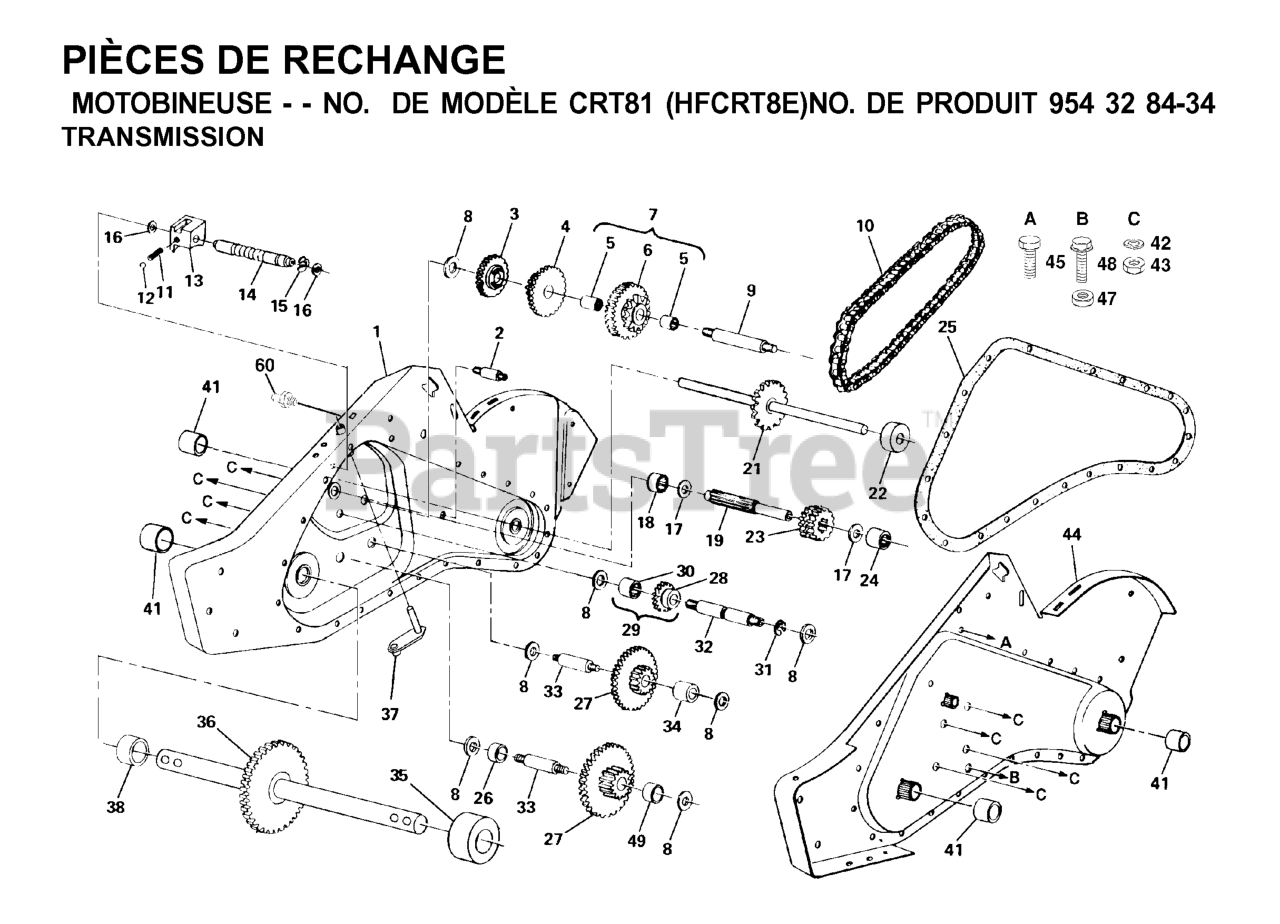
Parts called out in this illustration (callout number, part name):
1	GAERCASE.ASM.RH.W/BEARING
3	GEAR.REVERSE.8HP
5	BEARING.NEEDLE.CRT
6	SPROCKET ASMBLY, TINE
7	SPROCKET ASMBLY W/BEARINGS
9	SHAFT.REDUCTION.TILLER
10	CHAIN.ROLLER.TILLER
11	SPRING-SHIFT CRT
12	STEEL BALL KIT
13	SHIFT FORK TI
14	SHAFT.SHIFT.1.00 PINION
16	WASHER, SEAL (2 2)
17	THRUST WASHER
18	BEARING TI
19	SHAFT INPUT
21	SHAFT TINE CRT
22	SPACER 1.008X1-3/4X.645
23	GEAR.PINION
24	NEEDLE BRNG LT
25	RP GASKET, GEARCASE
27	GEAR, CLUSTER CRT
28	REVERSE GEAR
29	GEAR ASMBLY, REVERSE IDLER
30	NEEDLE BEARING TI
32	SHAFT, REVERSE IDLER
33	SHAFT, REDUCTION
34	SPACER.765 X 1.12 X .380.
35	SPACER, GROUND DRIVE RH
36	SHAFT ASSY CRT
37	BRACKET ASM.SHIFT.CRT
38	SPACER, GROUND DRIVE
41	SEAL ASM, OIL
42	LOCKWASHER
43	NUT.ASF.HEX.7/16
44	GEARCASE ASM, LH
45	SCREW
48	SCREW 5/16-18X4
60	ZERK M
